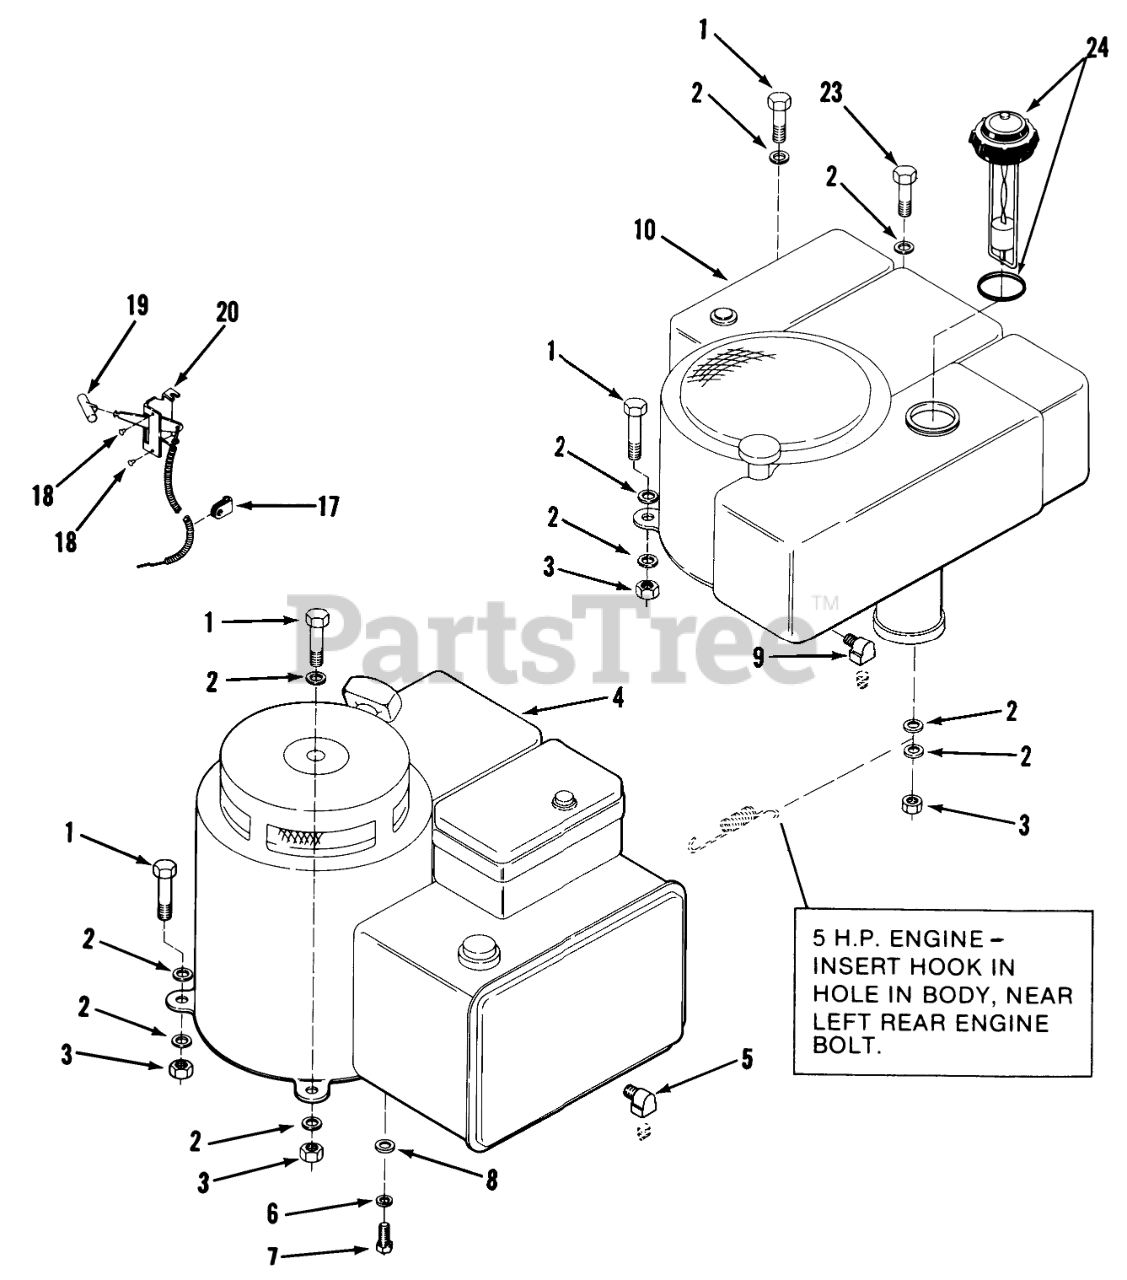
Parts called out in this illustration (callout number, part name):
2	WASHER 5/16 SAE
4	Engine 5 H.P.-B S Model 130902 Type 0584-01
5	Street Elbow
10	Engine 8 H.P.-B S Model 191707 Type 5639-2 A-81 Only
17	THROTTLE CONTROL CLP
18	RIVET
